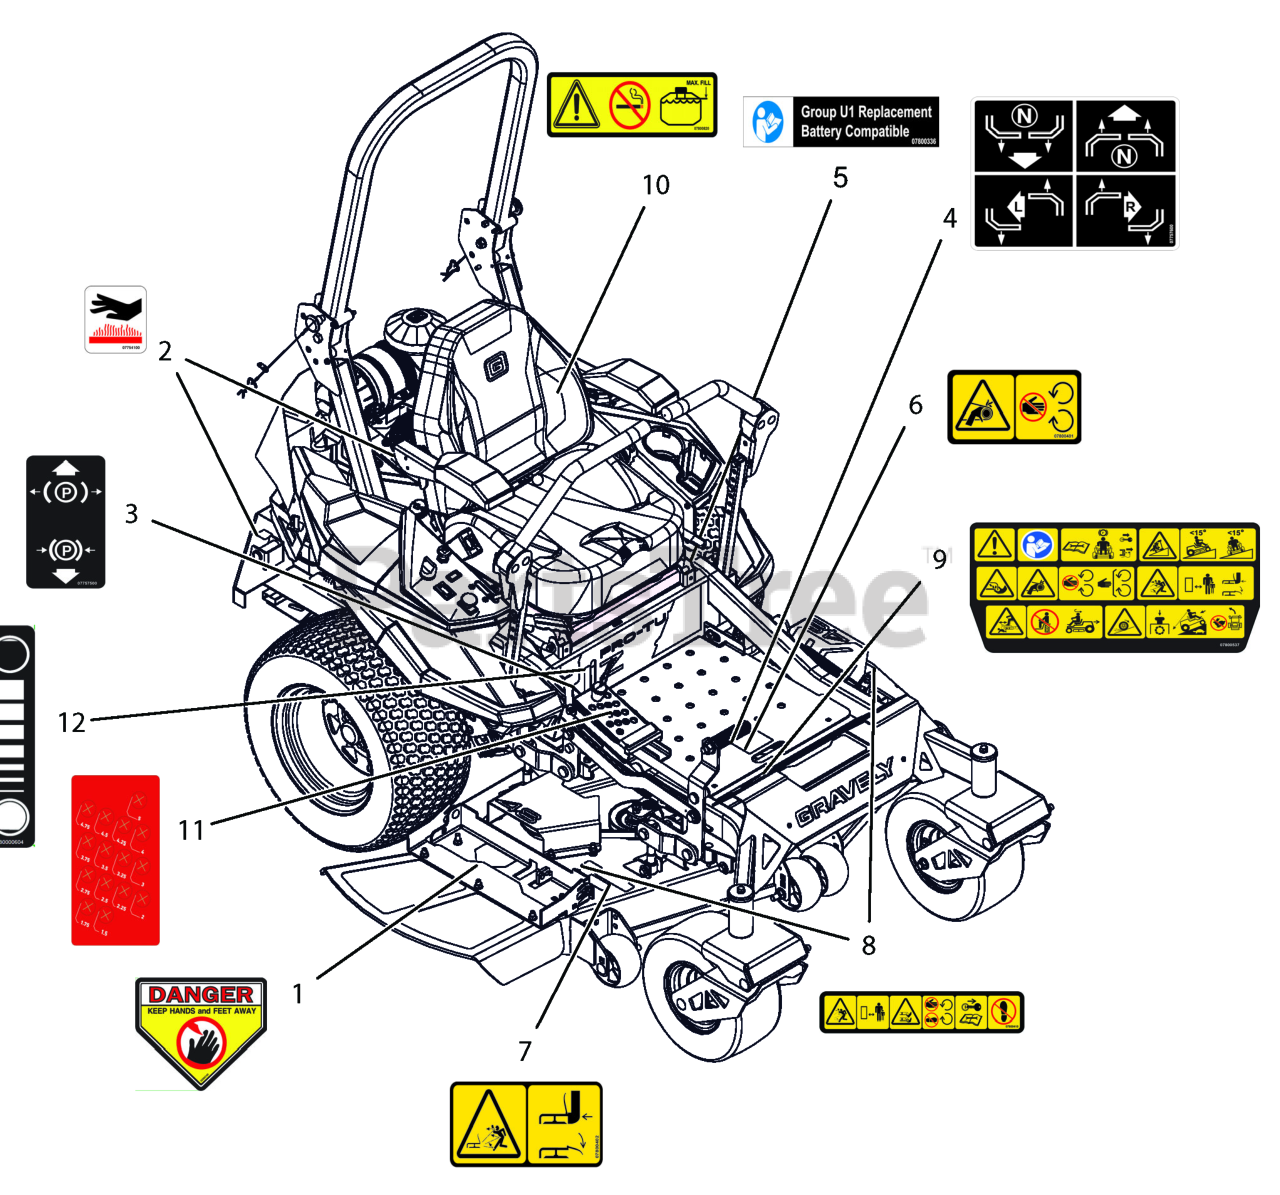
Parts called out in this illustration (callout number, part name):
1	DECAL, DANGER
2	DECAL, HOT SURFACE
3	DECAL, PARKING BRAKE LEVER
4	DECAL, INSTRUCTIONAL-STEERING
5	DECAL, U1 BATTERY REPLACEMENT
6	DECAL, SAFETY - GUARDING
7	DECAL, SAFETY - DECK GUARDING
8	DECAL, DECK SAFETY
9	DECAL, MAIN SAFETY
10	DECAL, FUEL WARNING
11	DECAL, HEIGHT OF CUT
12	DECAL, FUEL LEVEL
